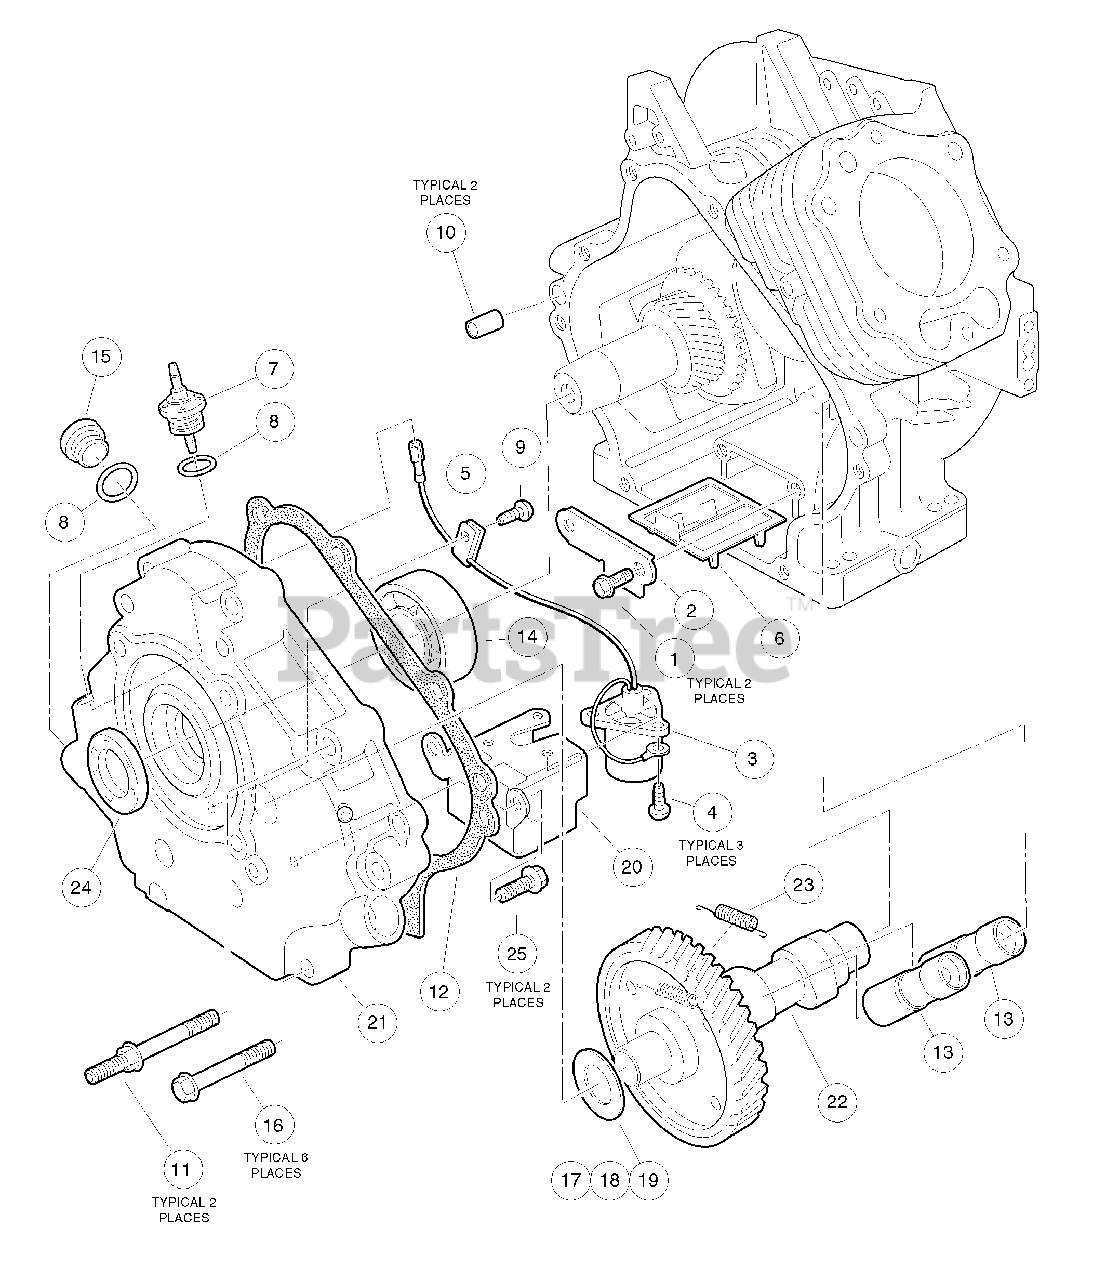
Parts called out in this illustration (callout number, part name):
1	Bolt, Flange Head, M5 x 0.8 x 8 mm
2	Plate, Oil Filter Screen
3	Sensor, Oil Level
4	Screw, Cross Pan-Head, M4 x 0.7 x 8 mm
6	Screen, Oil Filter
7	Connector, Cord
11	Bolt, Two-Ended, M8 x 1.25 x 69 mm
12	Gasket, Crankcase Cover
13	Adjuster, Lash
14	Bearinq, Ball
16	Screw, M8-1.25 X 45mm Hex
20	Switch Bracket
21	Cover, Crankcase, FE400
22	Camshaft, FE350/FE400 with ACR, 44-tooth
25	Bolt Switch Bracket
26	Kit, Gasket, FE400
